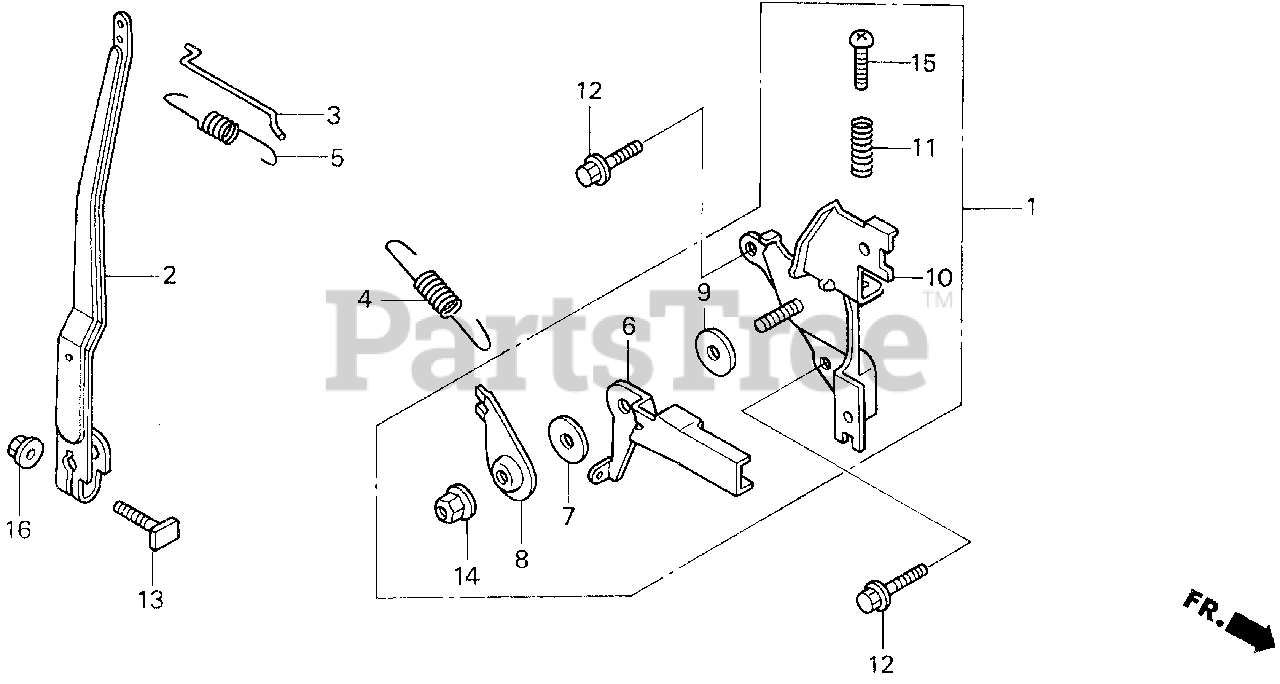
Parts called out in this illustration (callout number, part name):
1	CONTROL ASSY.
2	ARM, GOVERNOR
3	ROD, GOVERNOR
4	SPRING, GOVERNOR
5	SPRING, THROTTLE RETURN
6	LEVER, CONTROL
7	SPRING, LEVER
8	WASHER, CONTROL LEVER
9	SPACER, CONTROL LEVER
10	BASE, CONTROL
11	SPRING, CONTROL ADJUSTING
12	BOLT, FLANGE (5X12)
13	BOLT, GOVERNOR ARM
14	NUT, SELF-LOCK (6MM)
15	SCREW, PAN (5X20)
16	NUT, FLANGE (6MM)
